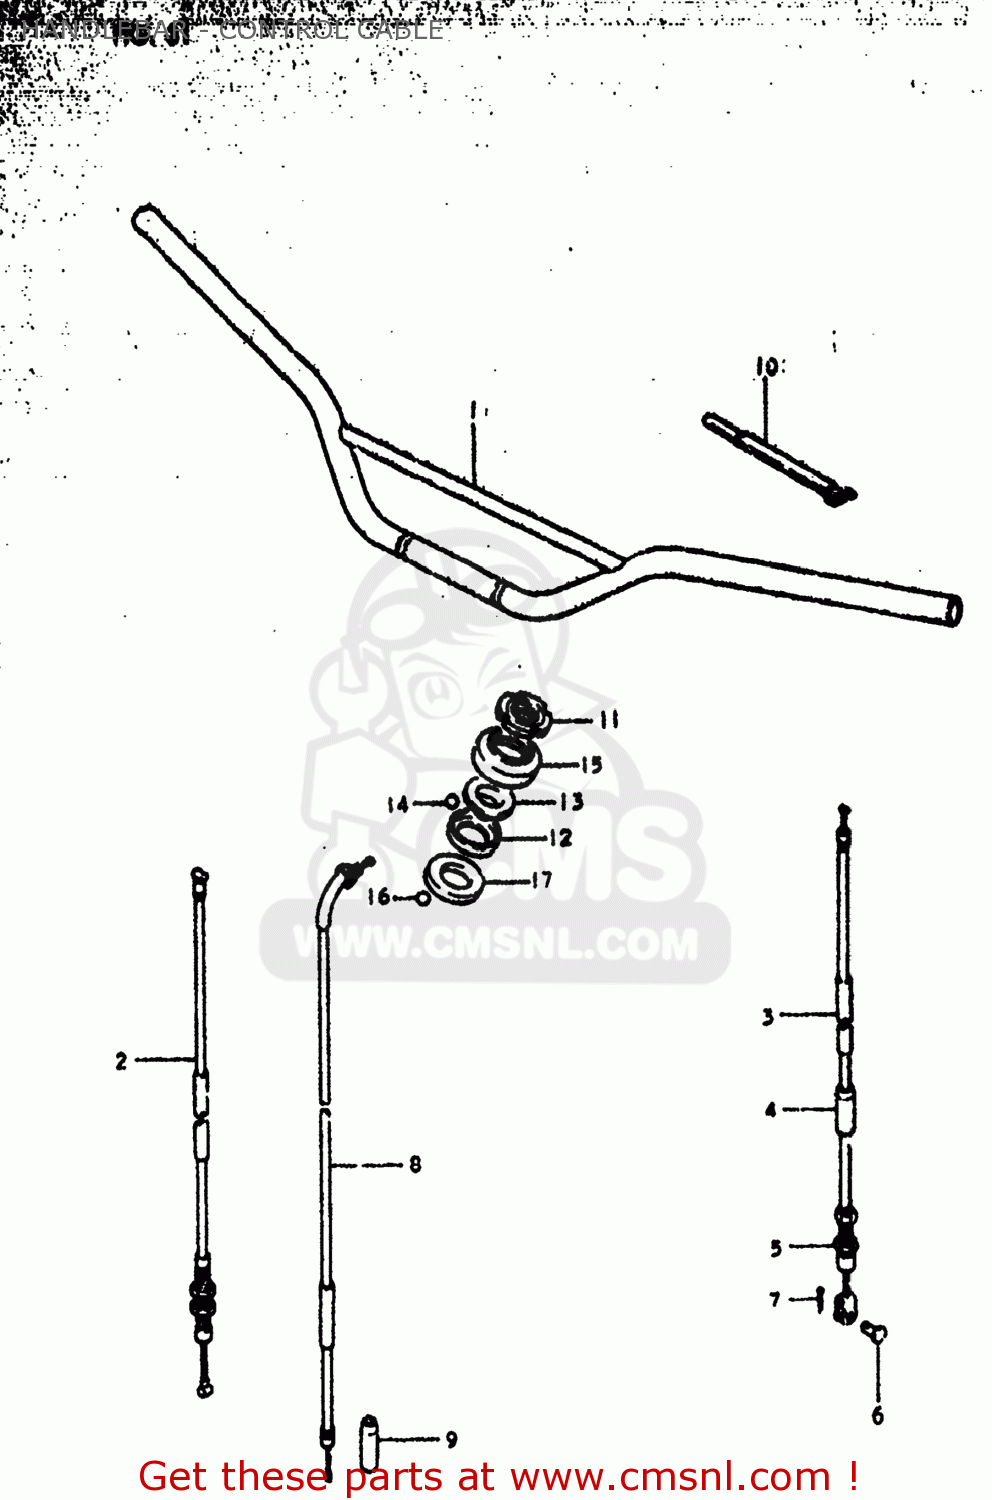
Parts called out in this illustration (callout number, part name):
1	HANDLEBAR
2	CABLE,FRONT BRAKE
3	CABLE ASSY,CLUTCH
4	SEAL,DUST(7X18X30)
5	NUT
6	PIN(L:13)
7	PIN
8	CABLE ASSEMBLY,THROTTLE
9	SEAL,DUST(7X18X30)
10	CLAMP
11	NUT,STEERING STEM(25X44X10)
12	RACE,STEERING INNER UPR
13	RACE,STEERING OUTER UPR
14	BALL
15	DUST SEAL,STEERING UPR
16	BALL
17	LACE,STEERING INNER LWR
